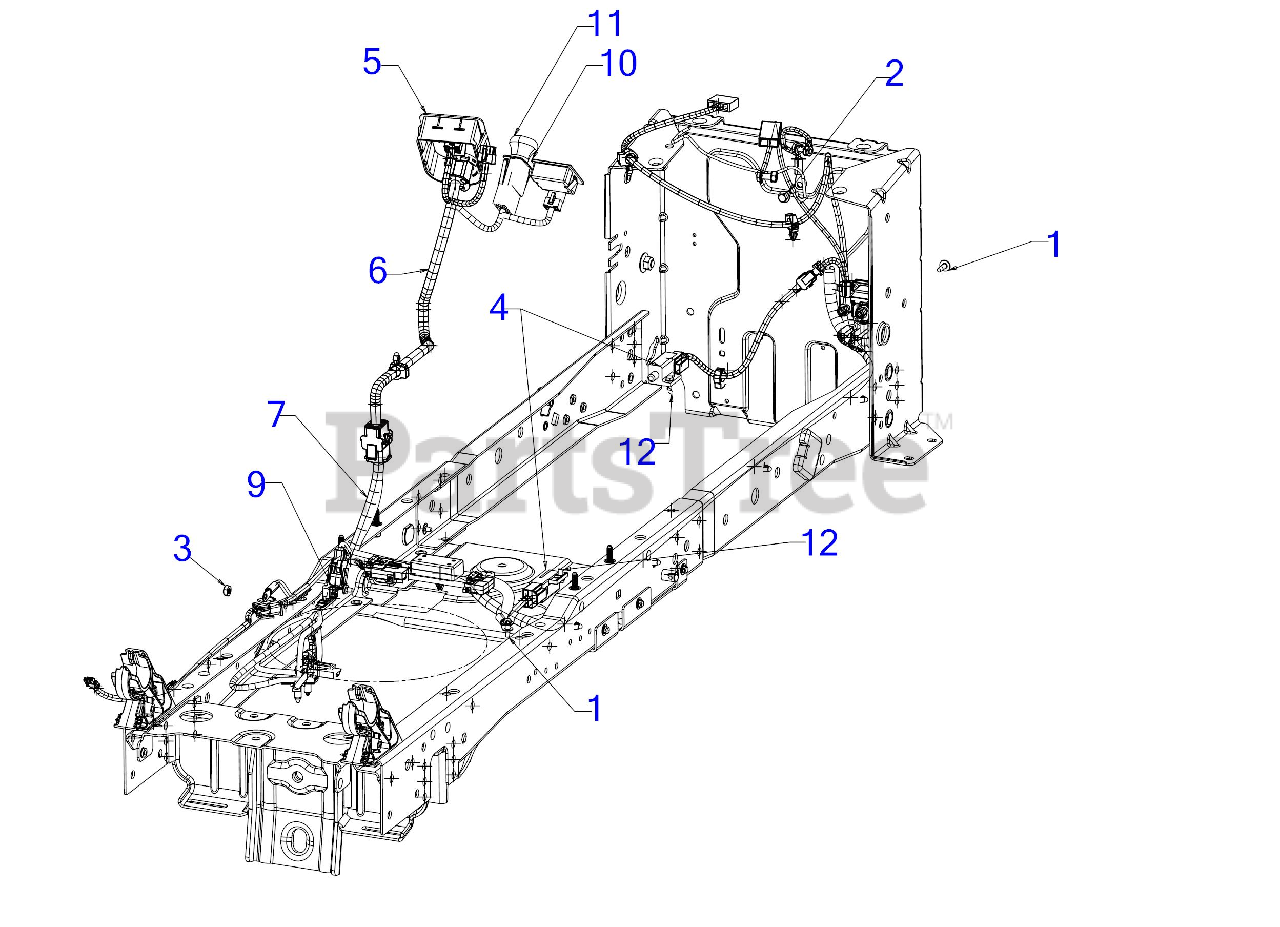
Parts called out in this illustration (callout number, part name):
1	SCREW M6-1 x .625
2	SCREW 1/4-20X.625
3	HEX NUT 1/4-20
4	INTERLOCK SWITCH (NO/NC)
5	IGNITION SWITCH MODULE
6	DASH HARNESS
7	MAIN HARNESS E-PTO/RMC/EPS
9	CLUTCH HARNESS 11"
10	SERVICE MNDR/HOUR METER- BLUETOOTH
11	PTO SWITCH (YELLOW KNOB)
12	SHOULDER SCREW
